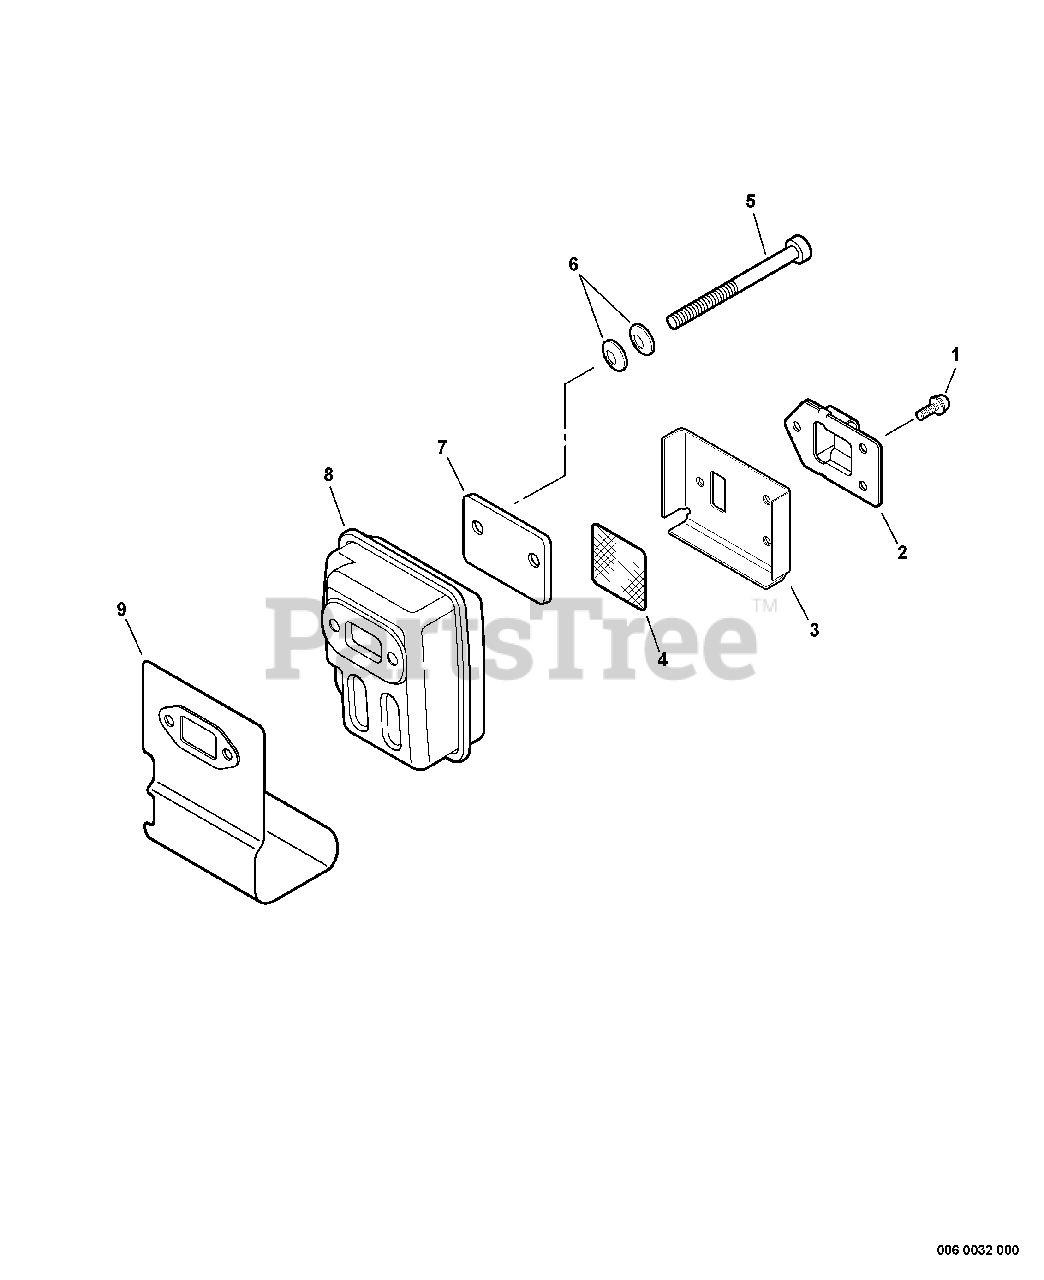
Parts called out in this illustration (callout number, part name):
1	SCREW - 4X12
2	GUIDE, EXHAUST
3	GASKET, EXHAUST
4	SCREEN, SPARK ARRESTOR
5	SCREW - 5X55
6	WASHER - CONICAL
8	MUFFLER
9	SHIELD, EXHAUST
